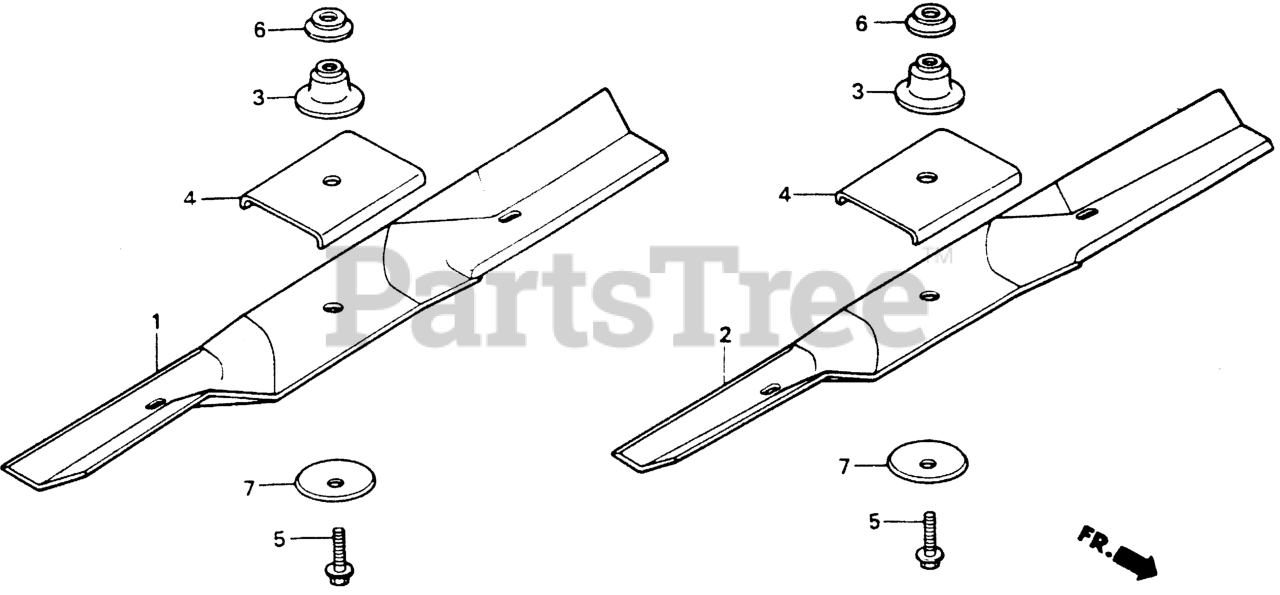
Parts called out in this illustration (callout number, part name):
1	BLADE, R. ROTARY
2	BLADE, L. ROTARY
3	HOLDER, BLADE
4	HOLDER, BLADE (B)
5	BOLT, BLADE HOLDER (10X28)
6	WASHER, BLADE HOLDER
